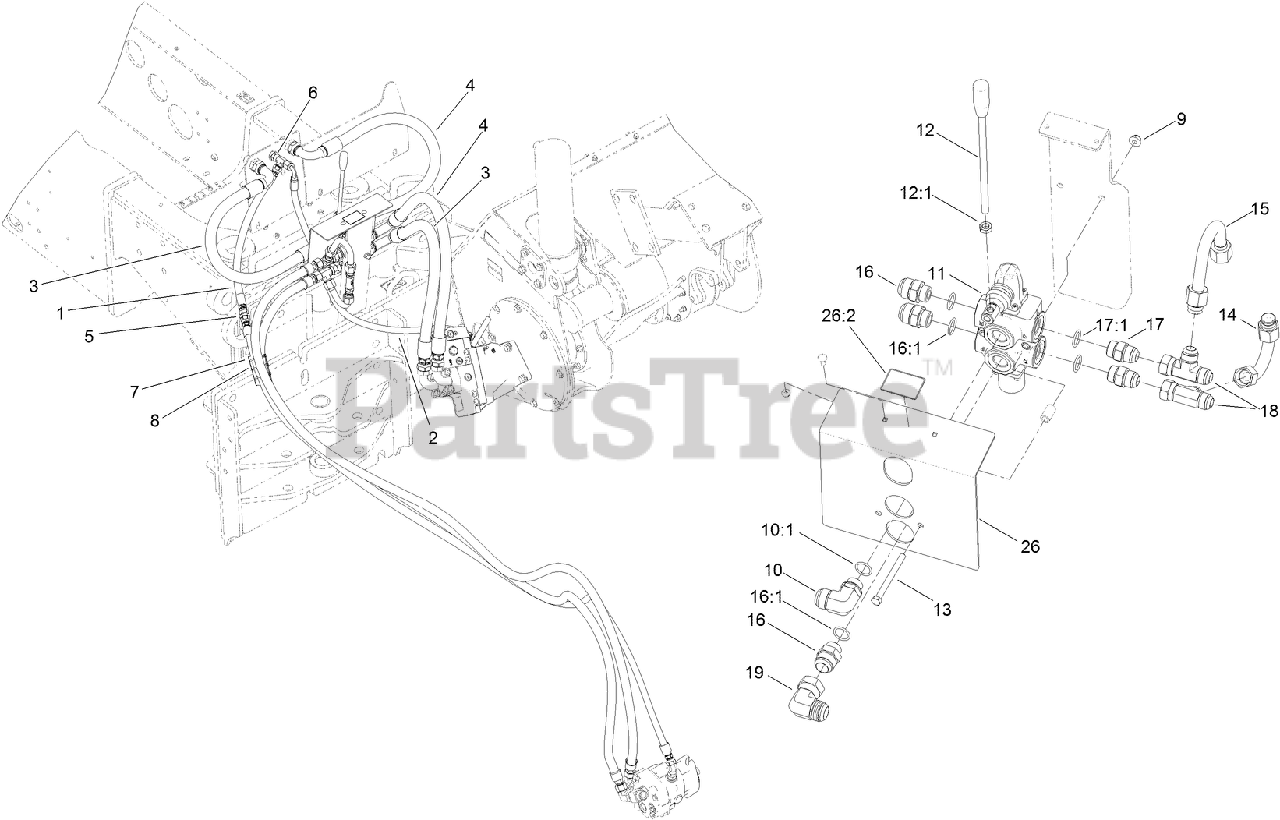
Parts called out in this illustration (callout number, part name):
1	HOSE ASM
2	HYD HOSE ASM
3	HOSE ASM
4	HOSE ASM
5	FITTING-UNION
6	FITTING-TEE
7	TIE-CABLE
8	PROTECTOR-HOSE
9	NUT-HF, NI
10	FITTING-ELBOW, 90
10:1	O-RING
11	VALVE-SELECTOR
12	HANDLE-SELECTOR, LONG
13	SCREW-HH
14	TUBE ASM
15	TUBE ASM
16	FITTING-STRAIGHT
16:1	O-RING
17	FITTING-STRAIGHT
17:1	O-RING
18	FITTING-TEE
19	FITTING-ELBOW, 90
26	GUARD PLATE ASM
26:2	DECAL-SELECTOR
